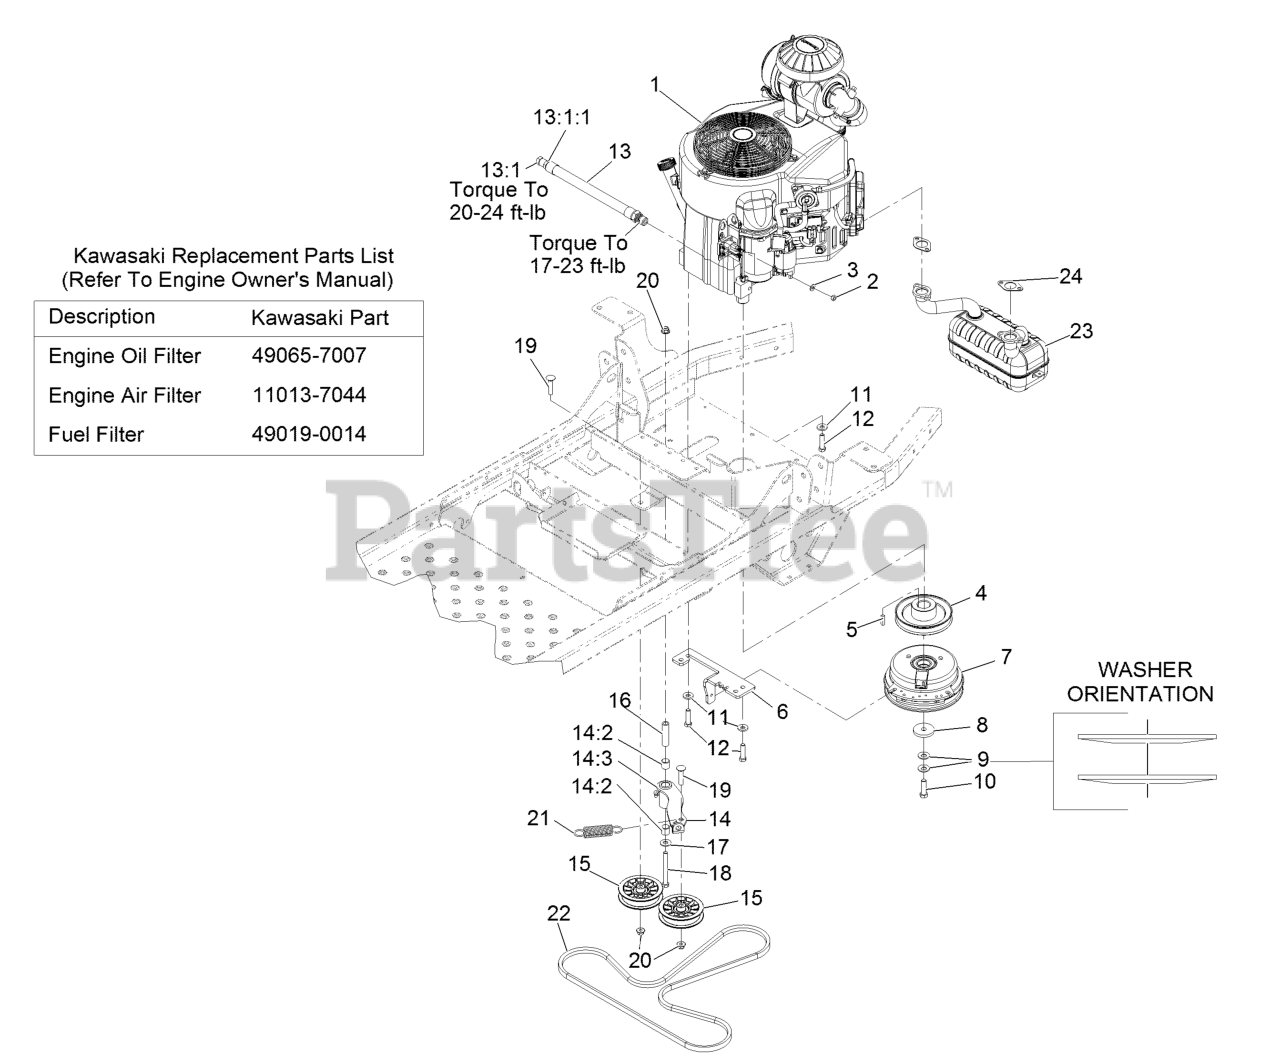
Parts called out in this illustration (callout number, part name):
2	NUT-HEX
3	WASHER-FLAT
4	SHEAVE-PUMP, DRIVE
6	ANCHOR-CLUTCH
8	WASHER-CLUTCH
9	WASHER-SPRING
10	SCREW-HH 7/16-20 X 1 1/2 W/LOCTITE
11	WASHER-BELLEVILLE
12	SCREW-HH
13	ENGINE OIL DRAIN HOSE ASM
13:1	PLUG-HH
13:1:1	O-RING
14:2	SLEEVE-BEARING
14:3	FITTING-GREASE, 90 DEG
15	PULLEY-FLAT IDLER
16	BUSHING-PIVOT, IDLER
17	WASHER-FLAT
18	SCREW-CARR
19	SCREW-CARR
20	NUT-HF, NI
21	SPRING-EXTENSION
22	V-BELT
23	MUFFLER-KAWASAKI
24	GASKET-EXHAUST
